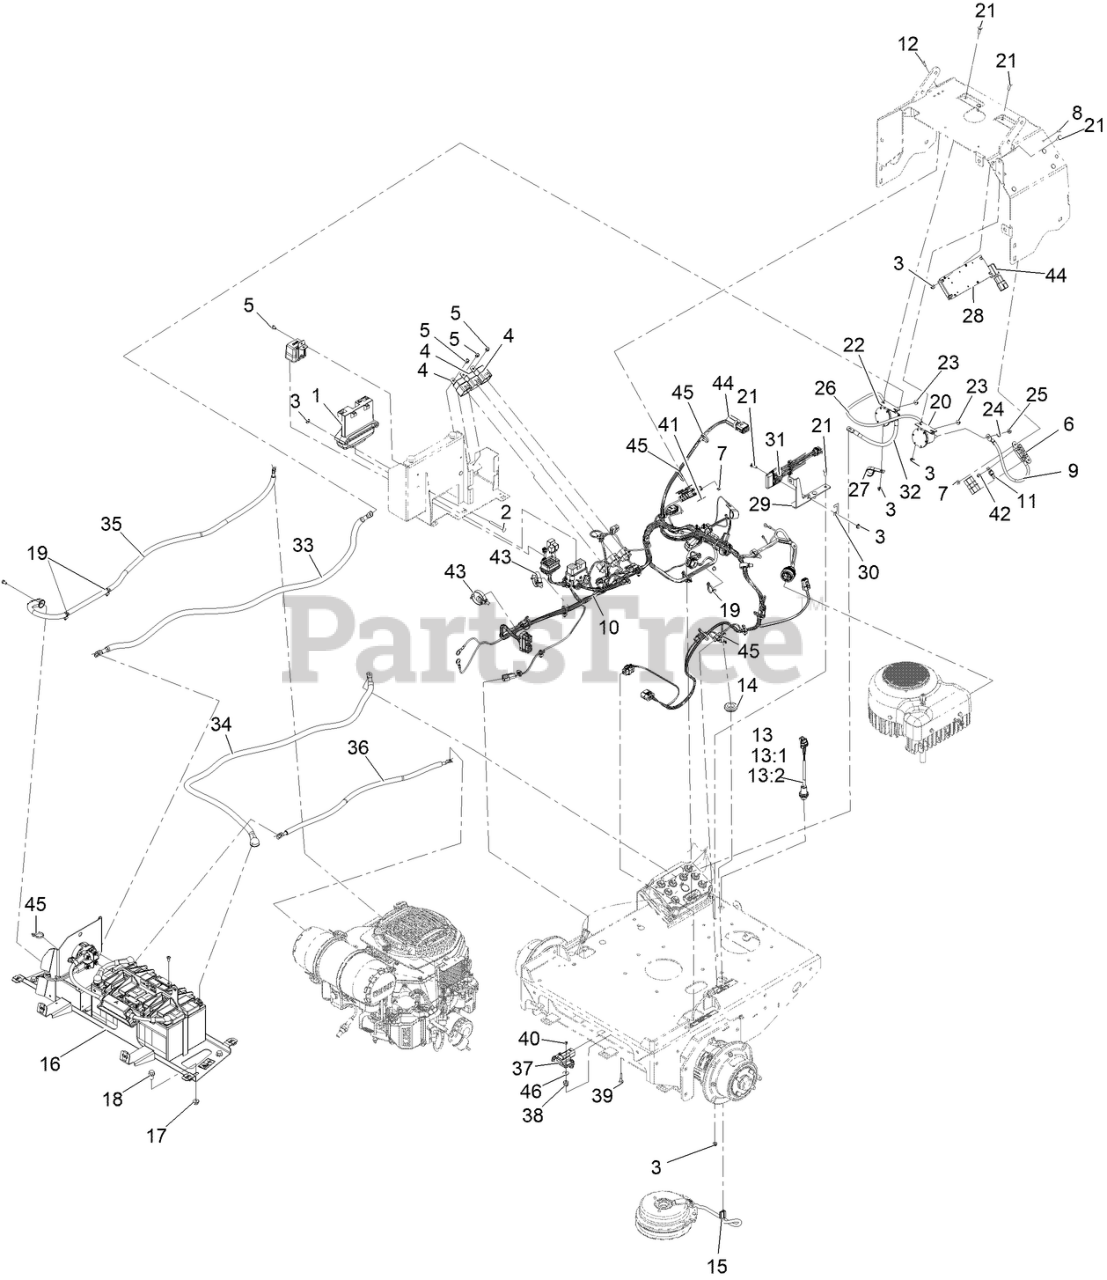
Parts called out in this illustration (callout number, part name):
1	Controller-Safety
2	SCREW-CARR
6	FUSE-HOLDER, MIDI FUSE
8	Bolt-CARR
9	CABLE-GEN, RD ASM
10	HARNESS-WIRE, CHASSIS
11	FUSE-80A
12	SCREW-HWH
13	PROXIMITY SWITCH ASM
13:1	NUT-HEX
13:2	WASHER-LOCK, INTERNAL TOO
14	GROMMET
15	HARNESS-CLUTCH PIGTAIL
16	Battery ASM
17	NUT-HF, NI
18	Screw-HH Flg 3/8-16 X 3/4
19	CLIP-TIE, FIR TREE W/TIE, 5MM/.196"" HOLE
20	Contactor-DC, 48V
21	BOLT-CARR
22	CONTACTOR-DC, 12V
23	NUT-KEPS
24	WASHER-LOCK
25	NUT-JAM
26	CABLE-CONT, RD ASM
27	CLIP-OPEN J, COATED
28	CONVERTER DC-DC
29	PLATE- CAN ISOLATOR MNT
30	Clip-Connector
31	Isolated Can Module ASM
32	CABLE-MTR CTR, RD ASM
33	CABLE-PWR, RD ASM
34	CABLE-GRND, BLK ASM
35	CABLE-GRND, BLK ASM
36	CABLE-PWR, RD ASM
37	Kit-Complete Imu
38	ISOLATOR-RUBBER
39	SCREW-SHOULDER
40	NUT-LOCK, NI
41	DECAL-FUSE,MAIN
43	Clip, Fir Tree W/Tie
44	FERRITE, SNAP-ON
45	TIE-CABLE
46	WASHER-FLAT
